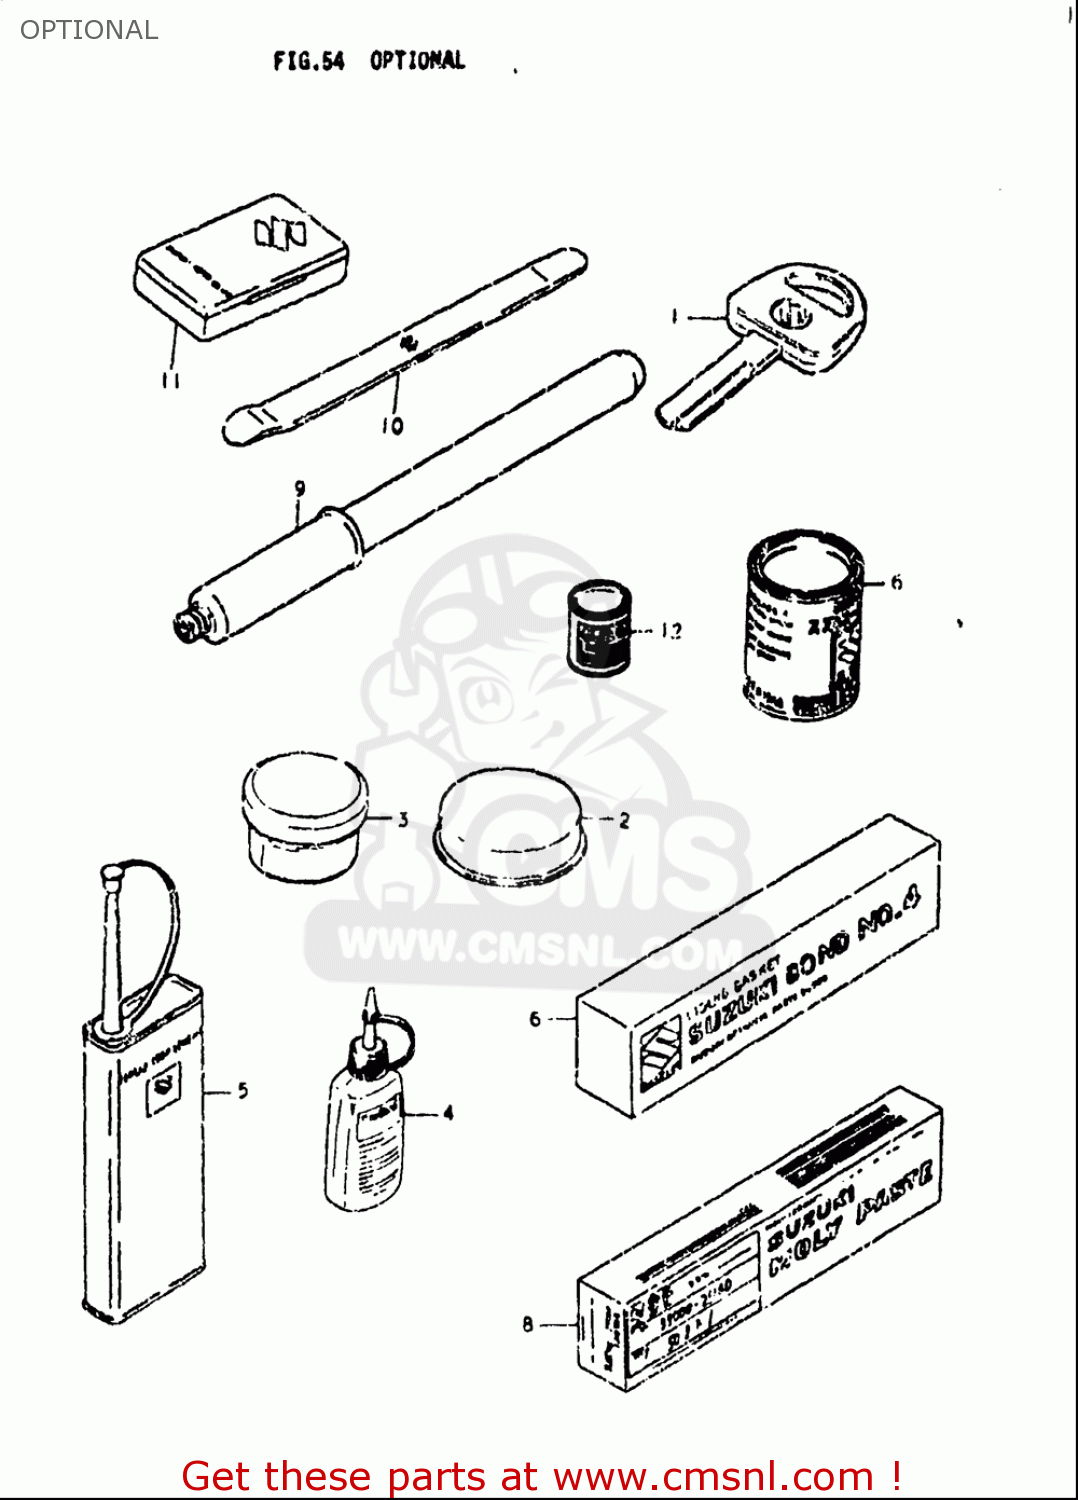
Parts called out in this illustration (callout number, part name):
1	KEY,BLANK
2	GREASE,PBC FOR BRK PAD 20G
3	GREASE,SILICON 20G
4	THREAD LOCK NO.1303B PURPL 50G
5	THREAD LOCK NO.1401 CLEAR 200G
6	BOND 1104
7	GREASE(C)EP2 LITHIUM 150G
8	SUZUKI MOLY PASTE
10	LEVER,TIRE
13	GASKET SET (NAS)
